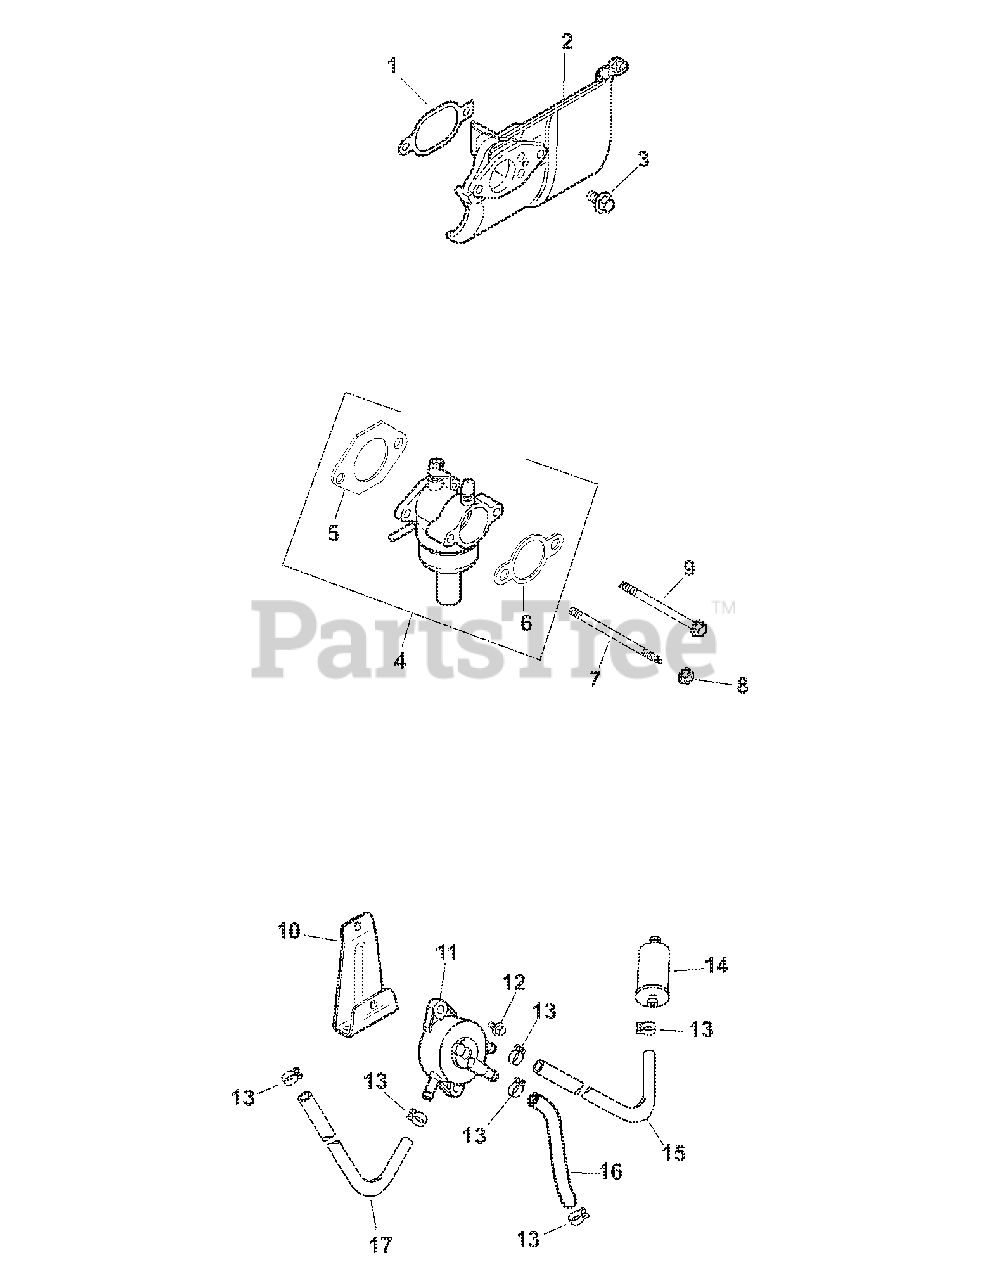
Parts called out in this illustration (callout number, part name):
1	Heat Deflector Gasket
2	Heat Deflector
3	Hex Flange Screw (M6 x 1.0 x 20)
4	Carburetor w/Gaskets
5	Carburetor Gasket
6	Air Cleaner Gasket
7	Carb Mounting Stud
8	Hex Flange Nut (M6 x 1.0)
9	Carb Screw (S60 x 1.42 x 85)
10	Fuel Pump Mounting Bracket
11	Fuel Pump Assembly
12	Hex Flange Screw (M5 x .8 x 10)
13	Hose Clamp
14	Fuel Filter
15	Fuel Line 4"
16	Fuel Line 10"
17	Fuel Line 15-3/4"
